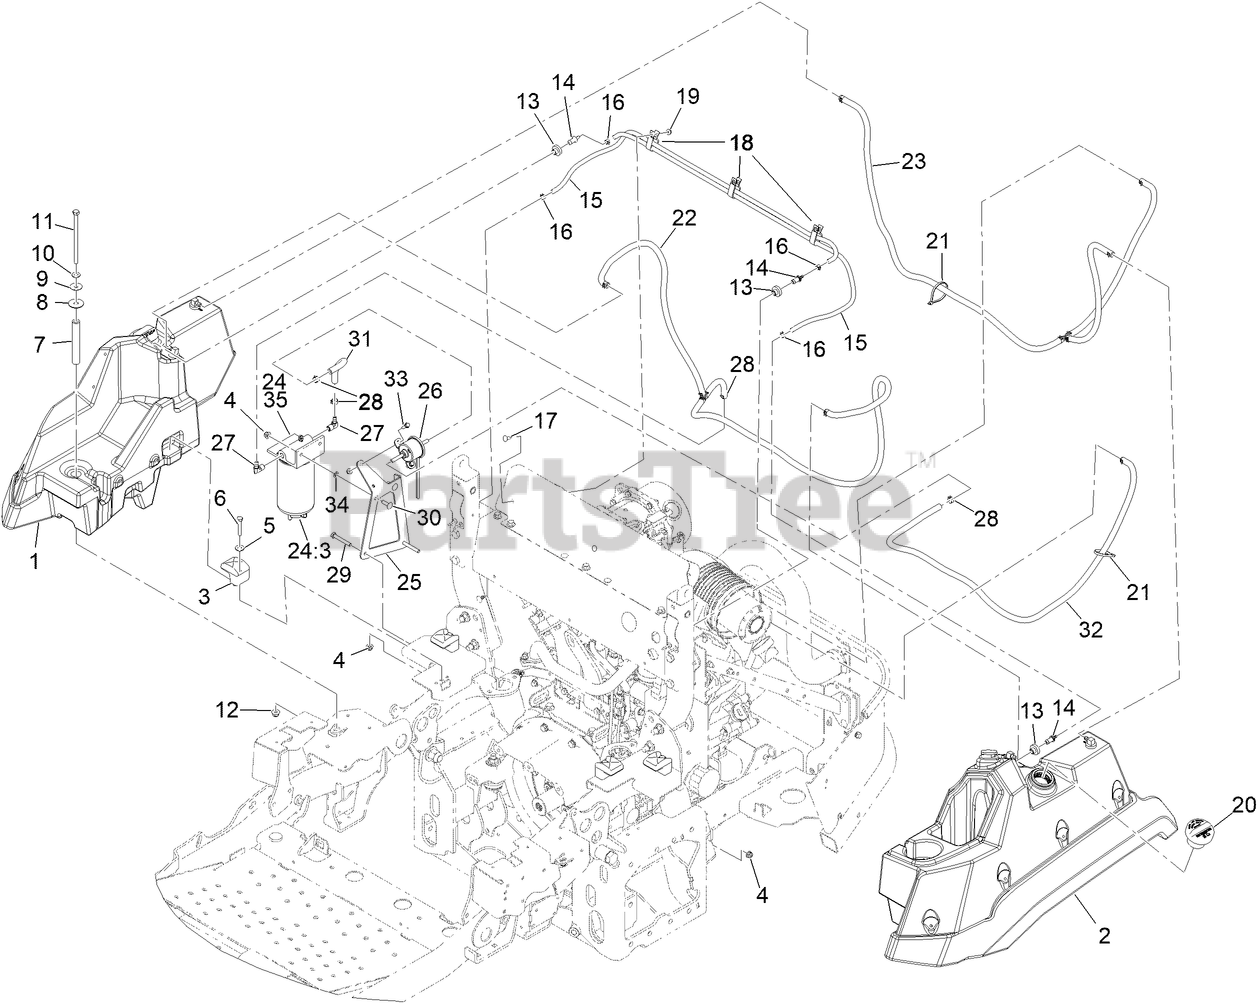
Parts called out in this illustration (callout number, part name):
1	RH FUEL TANK ASM
2	ASM-FUEL TANK, LH
4	NUT-HF, NI
5	WASHER-FLAT
6	SCREW-HH
7	TUBE-SPACER
8	WASHER-RUBBER
9	WASHER-PLAIN
10	WASHER-FLAT
11	SCREW-HH
12	NUT-HF, NI
13	BUSHING
14	FITTING-ORIFICE, STRAIGHT
15	HOSE-VENT, TANK
16	CLAMP-HOSE
17	SCREW-CARR
18	CLAMP-HOSE
19	NUT-HF
20	CAP-FUEL, DIESEL ULTRA LOW SULFUR
21	TIE-CABLE
22	FUEL SUCTION LINE ASM
23	FUEL RETURN LINE ASM
24	FILTER-FUEL/WATER SEPARATOR
24:3	FILTER-BOWL, WATER SEPARATOR
25	BRACKET-FILTER, FUEL
26	PUMP-FUEL, ELECTRIC
27	FITTING-HYD, 90
28	CLAMP-HOSE
29	SCREW-HH
30	SCREW-CARR
31	HOSE-FUEL
32	HOSE-FUEL
33	SCREW-HWH
34	RING-RETAINING, BOLT
35	FILTER-FUEL/WATER SEPARATOR
